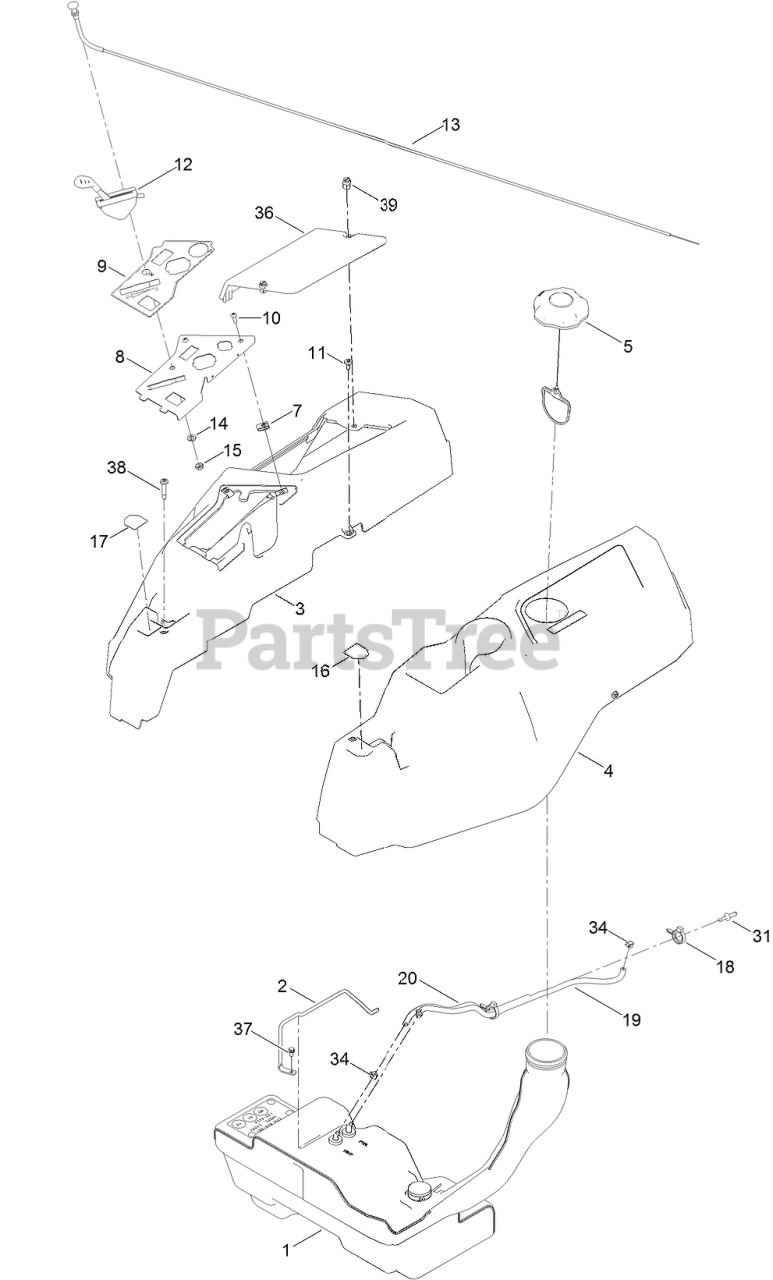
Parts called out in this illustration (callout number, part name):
1	FUEL TANK ASM
2	ROD-HOLD DOWN
3	POD-RH
4	POD-LH
5	CAP-FUEL, RATCHETING
8	PANEL-CONTROL
9	DECAL-CONTROL W/CHOKE
10	SCREW-PRH
11	SCREW-SHOULDER
12	CABLE-THROTTLE
13	CABLE-CHOKE
14	WASHER-LOCK
15	NUT-HJ
16	DECAL-LEVER, CONTROL (LH)
17	DECAL-LEVER, CONTROL (RH)
18	CLAMP-HOSE
19	HOSE-FUEL
20	HOSE-FUEL
31	ADAPTOR-ORIFICE
34	CLAMP-HOSE
36	COVER-BATTERY
37	SCREW-HWH
38	SCREW-SHOULDER
39	FASTENER
